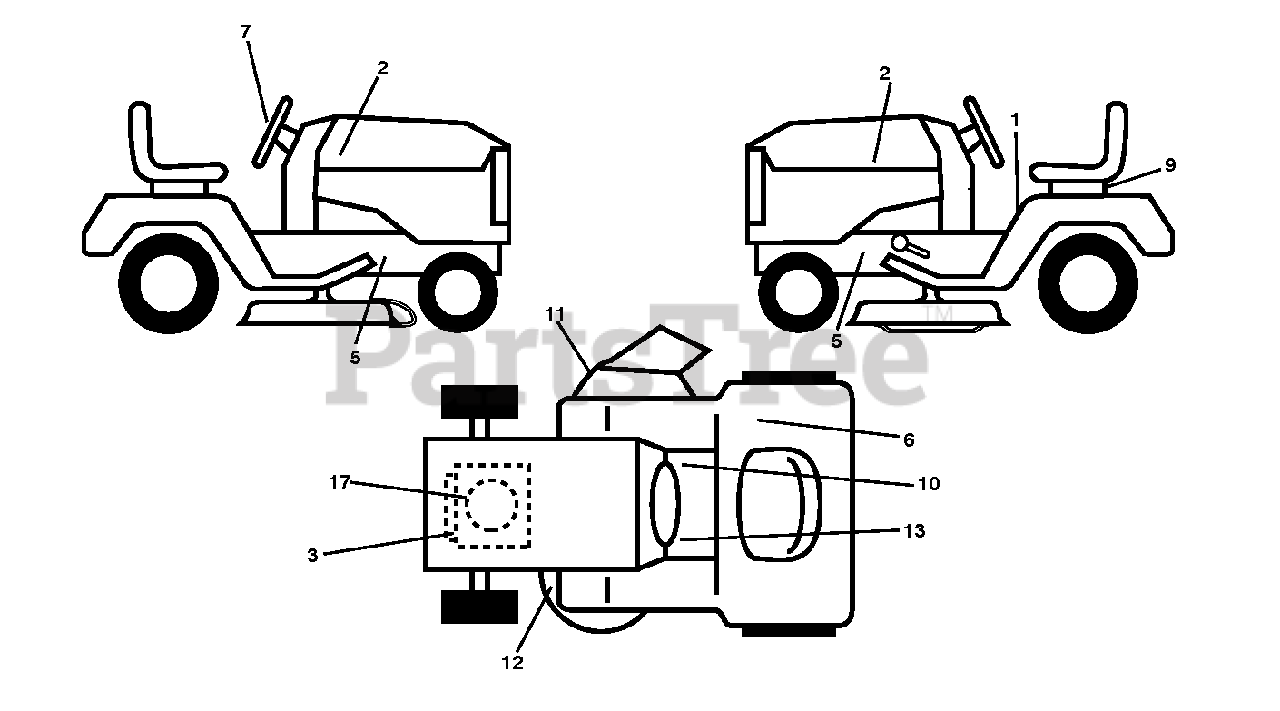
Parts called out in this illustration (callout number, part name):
6	Decal, 100 DB/CE
9	DECAL BTRY SYMBOLS
10	DECAL PARK BRAKE
11	DECAL, WARN. DEFLECT/CTFGR
